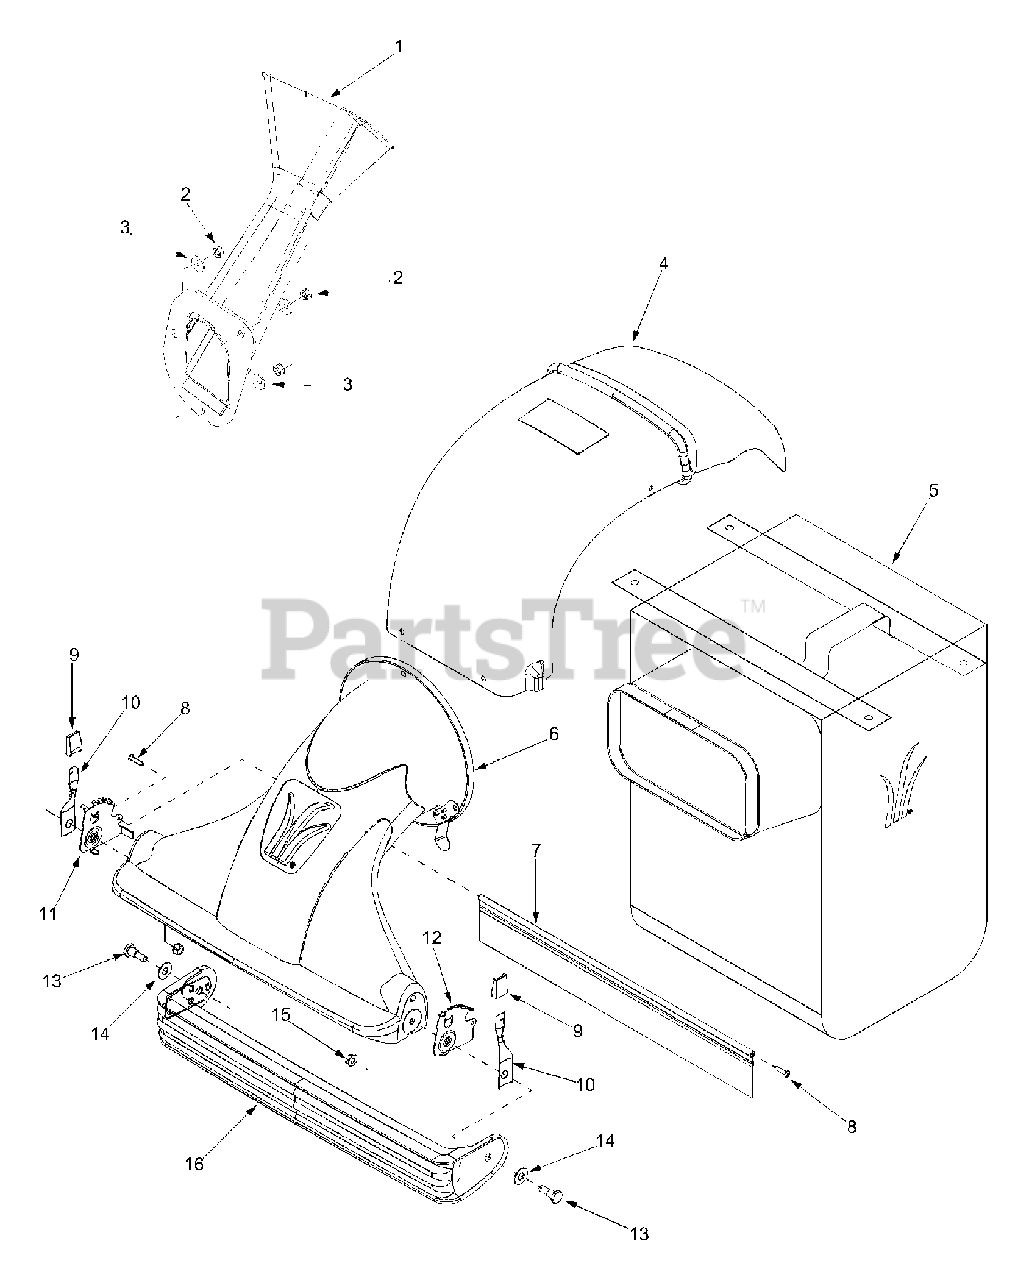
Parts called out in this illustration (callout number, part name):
2	Hex Nut 5/16-18
3	Bell Washer .340 ID x .872 OD
4	Discharge Chute
5	Bag
6	Nozzle Assembly
7	Nozzle Flap
8	Screw
9	Height Adjustment Knob
10	Spring Lever
13	Shoulder Screw
14	Flat Washer .510 x 1.12 x .060
15	Hex Flange Lock Nut 3/8-16
16	Door Assembly
